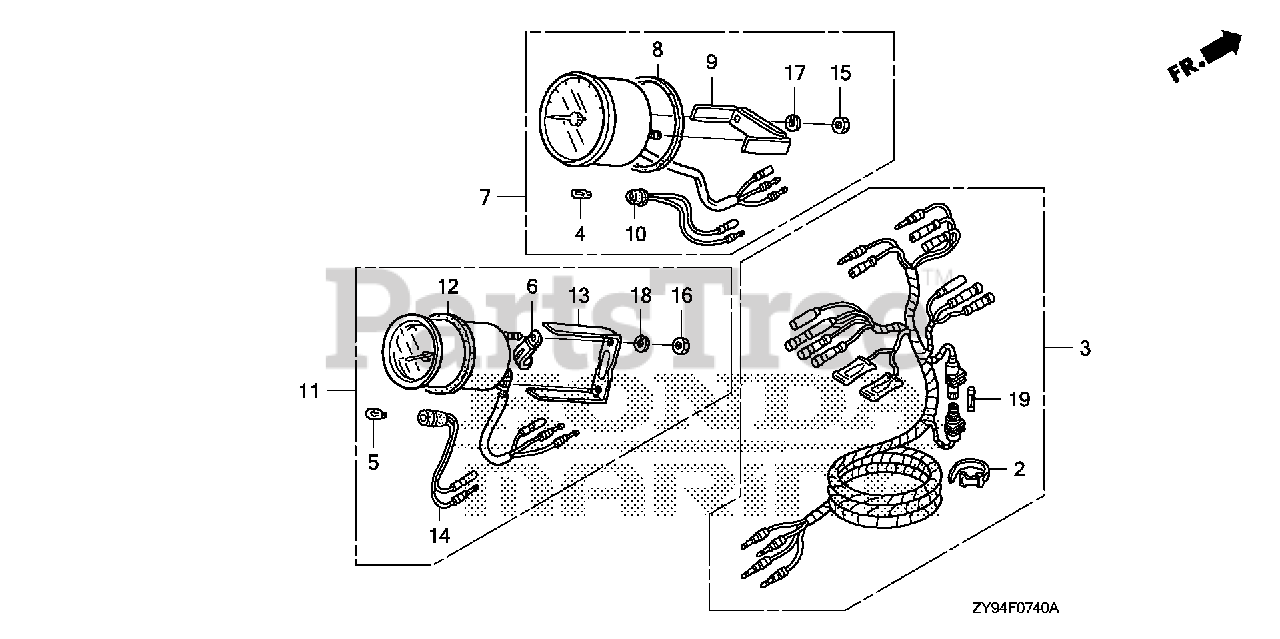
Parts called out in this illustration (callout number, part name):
2	BAND B1, CABLE Use up to Frame SN 1001879.
3	HARNESS ASSY., METER (A)
4	BULB, WEDGE BASE (T10) (12V 1.7W) (STANLEY)
5	BULB, WEDGE BASE (12V1.7W) (TOSHIBA)
6	CLAMP
7	TACHOMETER ASSY.
8	GASKET
9	BRACKET (TO 1015209) (FROM 1015210)
10	SOCKET (TO 1015209) (FROM 1015210)
11	METER ASSY., TRIM
12	GASKET (TO 1015209) (FROM 1015210)
13	BRACKET (TO 1015209) (FROM 1015210)
14	SOCKET (TO 1015209) (FROM 1015210)
15	NUT, HEX. (5MM)
16	NUT, HEX. (4MM)
17	WASHER, SPRING (5MM)
18	WASHER, SPRING (4MM)
19	FUSE A (10A)
